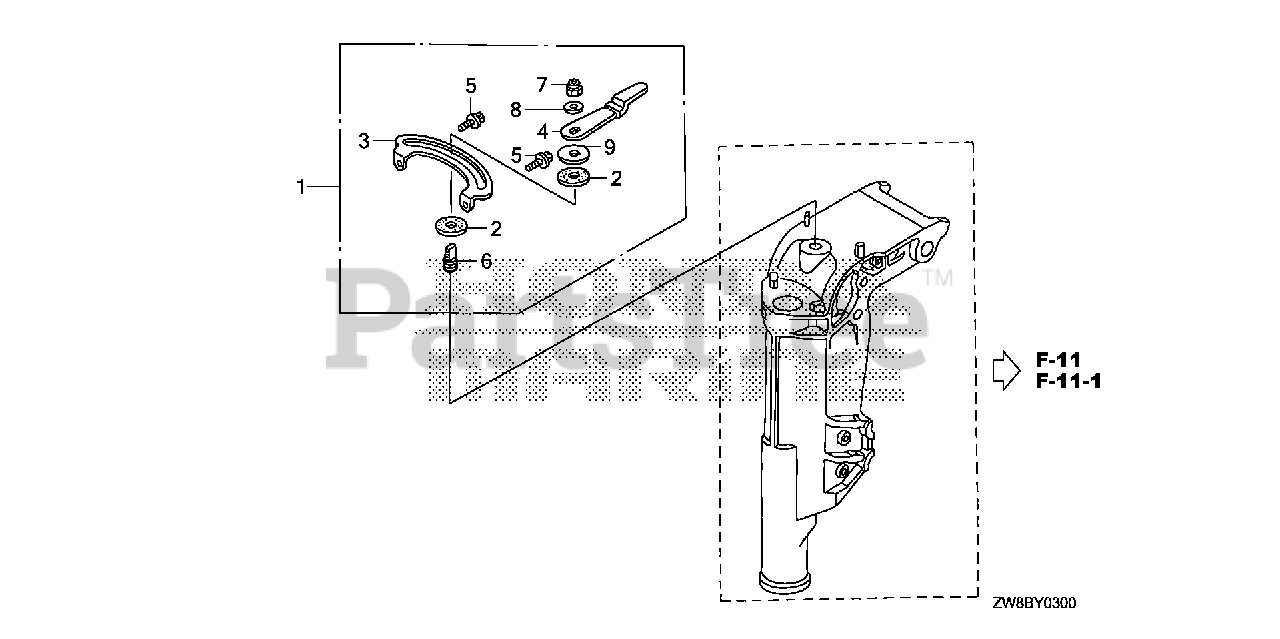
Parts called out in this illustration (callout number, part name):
1	STEERING KIT, FRICTION
2	BLOCK, FRICTION
3	PLATE, FRICTION
4	LEVER, FRICTION
5	BOLT, FLANGE (6X12)
6	BOLT, STUD (8X26)
7	NUT, SELF-LOCK (8MM)
8	WASHER (8MM)
9	WASHER, NYLON (8MM)
